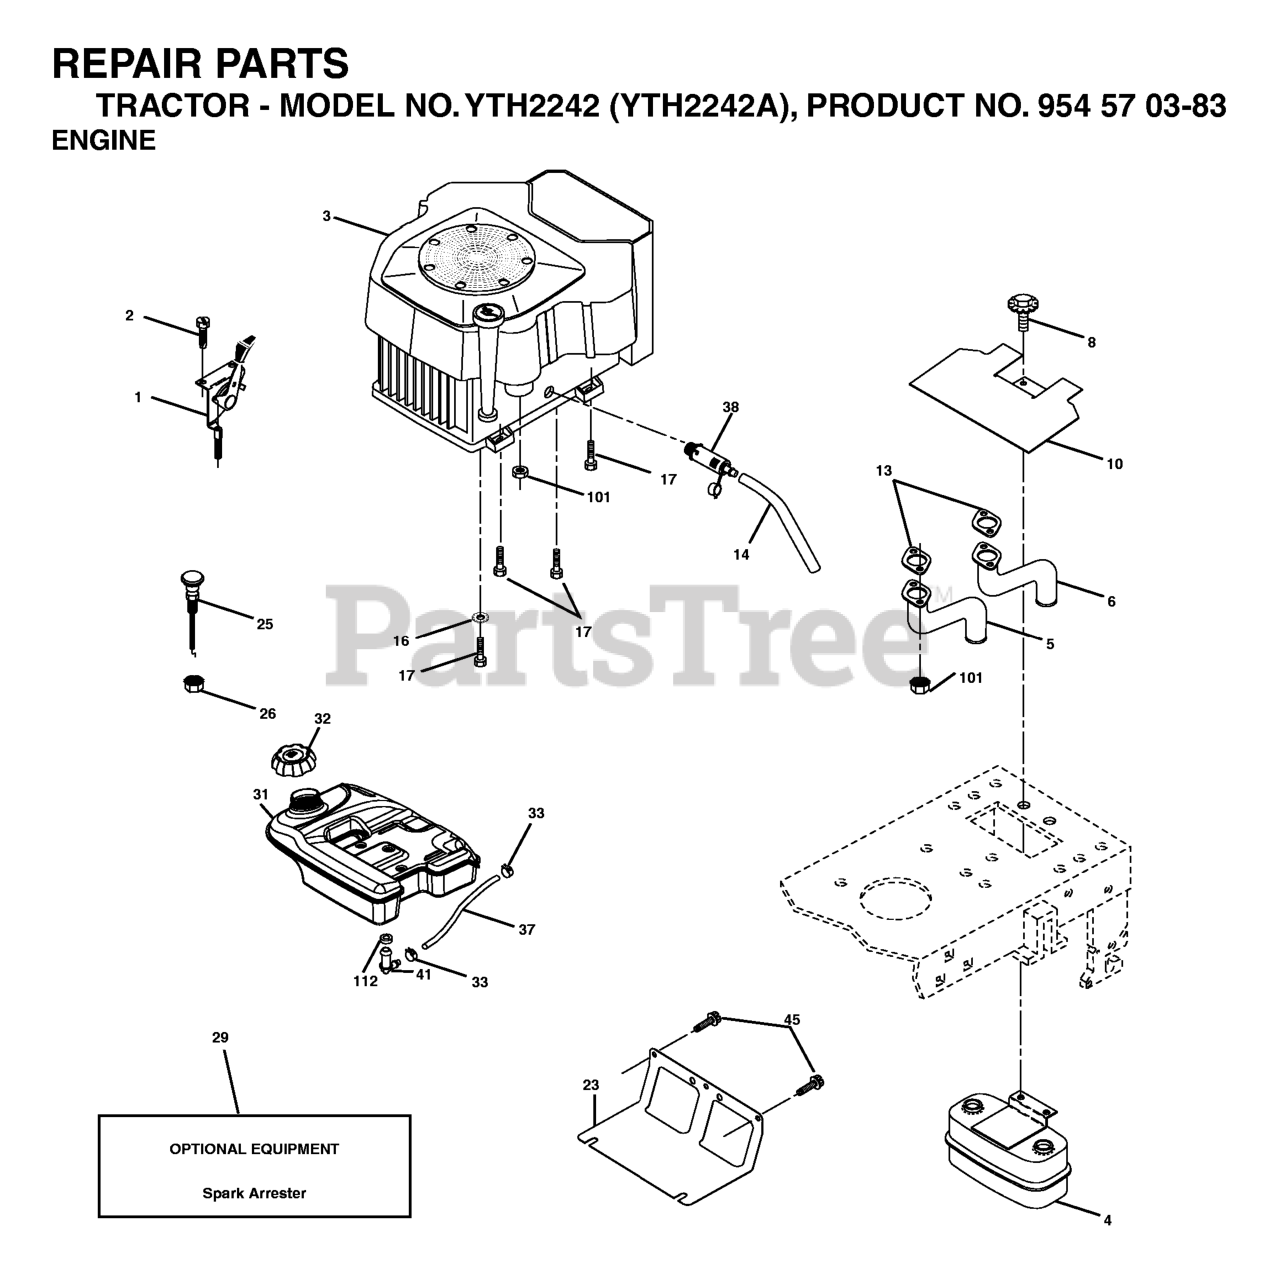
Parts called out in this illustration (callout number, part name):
1	CONTROL,TH/CH FLAG
2	SCREW
4	MUFFLER.TWIN.CYL.LOW.TONE
5	RP.PIPE-EXHAUST LH
6	RP.PIPE-EXHAUST RH
8	BOLT.5/16-18UNCX3/4 W/SEMS.BLK
10	RP SHIELD HEAT MUFFLER
13	GASKET.EXHAUST.KOHL.CV18-CV26
14	TUBE, DRAIN OIL ASM.
16	LOCKWASHER
17	SCREW 3/8-16 X 1-1/2
23	SHIELD.BROWNING.DBR.GUARD
25	CONTROL, CHOKE
26	Nut Keps 3/8 - 24 UNF
29	KIT.SPARK ARRESTOR 794945 B&S
31	4.0 REAR FUEL TANK
32	TANK CAP
33	HOSE CLAMP
37	REPL BY 532 00 85-43
38	PLUG DRAIN OIL EASY
41	STEM FUEL TANK
45	SCREW, 3/8-16X3/4
101	FLANGE NUT
112	BUSHING OUTLET T
